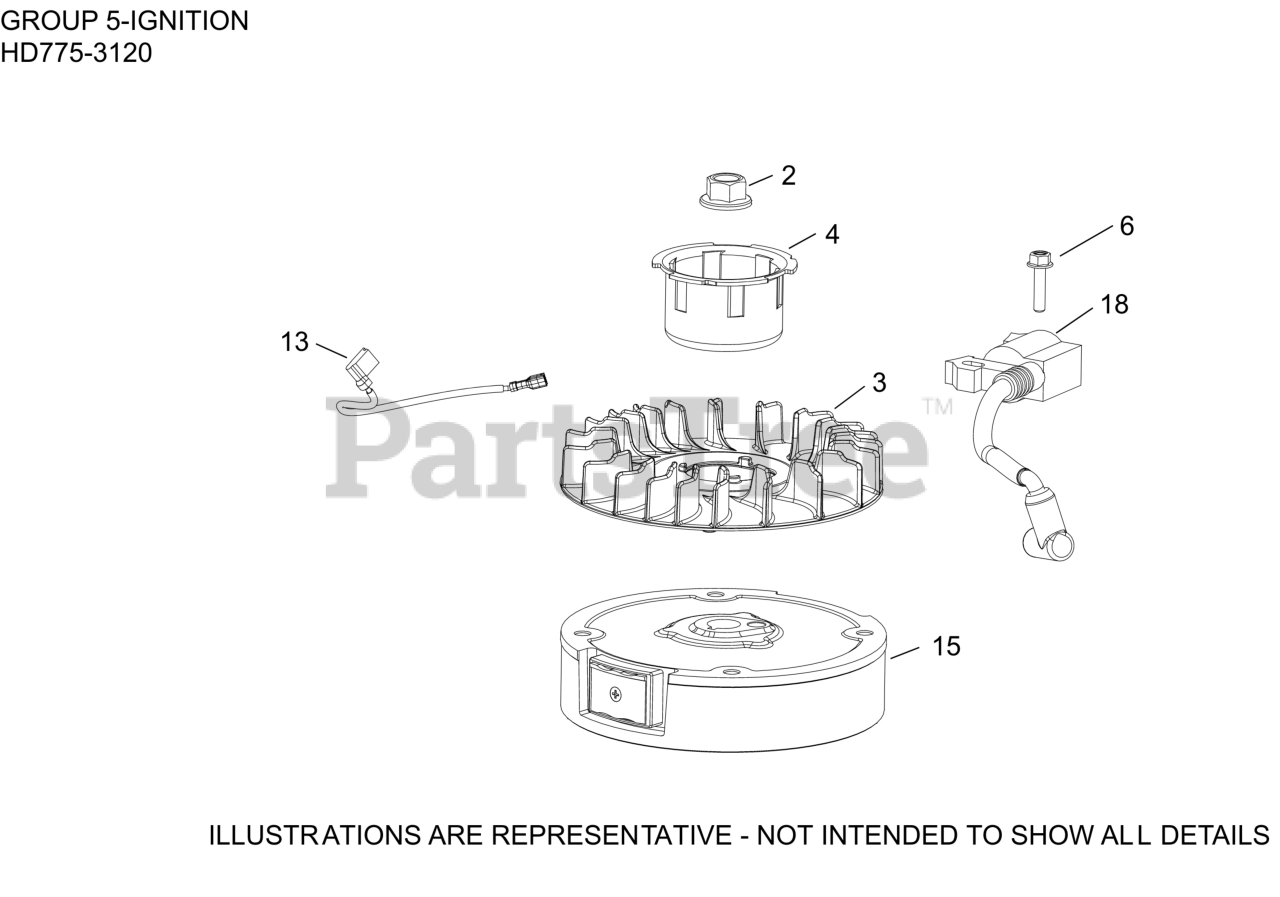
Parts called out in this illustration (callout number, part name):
2	NUT, FLYWHEEL (W/SERRATIONS)
3	FAN, FLYWHEEL
4	CUP, DRIVE - (#1410905S)
6	SCREW, M6 X 25-(#25086436S)
15	FLYWHEEL (CAST IRON)
18	MODULE IGNITION CAST IRON FLYWHEEL
